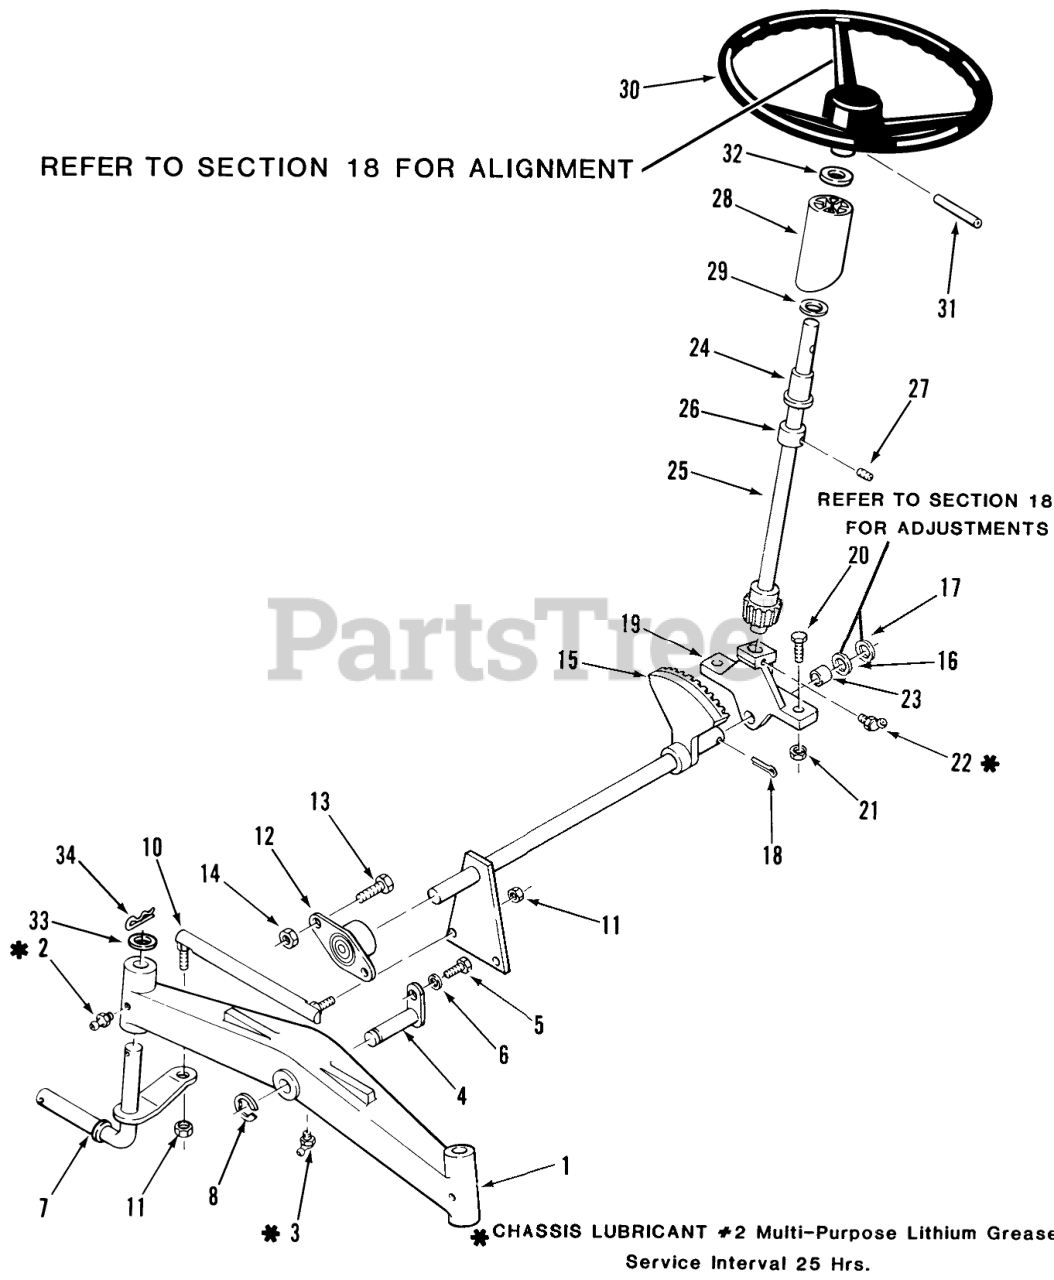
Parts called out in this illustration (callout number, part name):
1	AXLE-FRONT
2	Zerk
3	FITTING-GREASE
4	PIN AND PLATE ASM
5	H H C S
6	Lockwasher
7	Front Spindle RH
7	Front Spindle LH
8	E-RING
10	Tie Rod RH
10	Tie Rod LH
11	NUT-6
12	BEARING-FLANGED
13	Bolt
14	Nut
15	Assy-Steering
16	WASHER-SHIM
17	WASHER
18	PIN-4
19	Support
20	BOLT
21	Nut
22	FITTING-GREASE
23	BEARING-BRONZE
24	BEARING-FLANGED
25	Shaft-Upper Steering
26	Collar
27	SCREW-SET
28	Collar
29	WASHER-BOWED
30	STEERING WH 13" PLAS
31	Pin-Roll
32	WASHER-FLAT
33	WASHER
34	COTTER PIN-4
